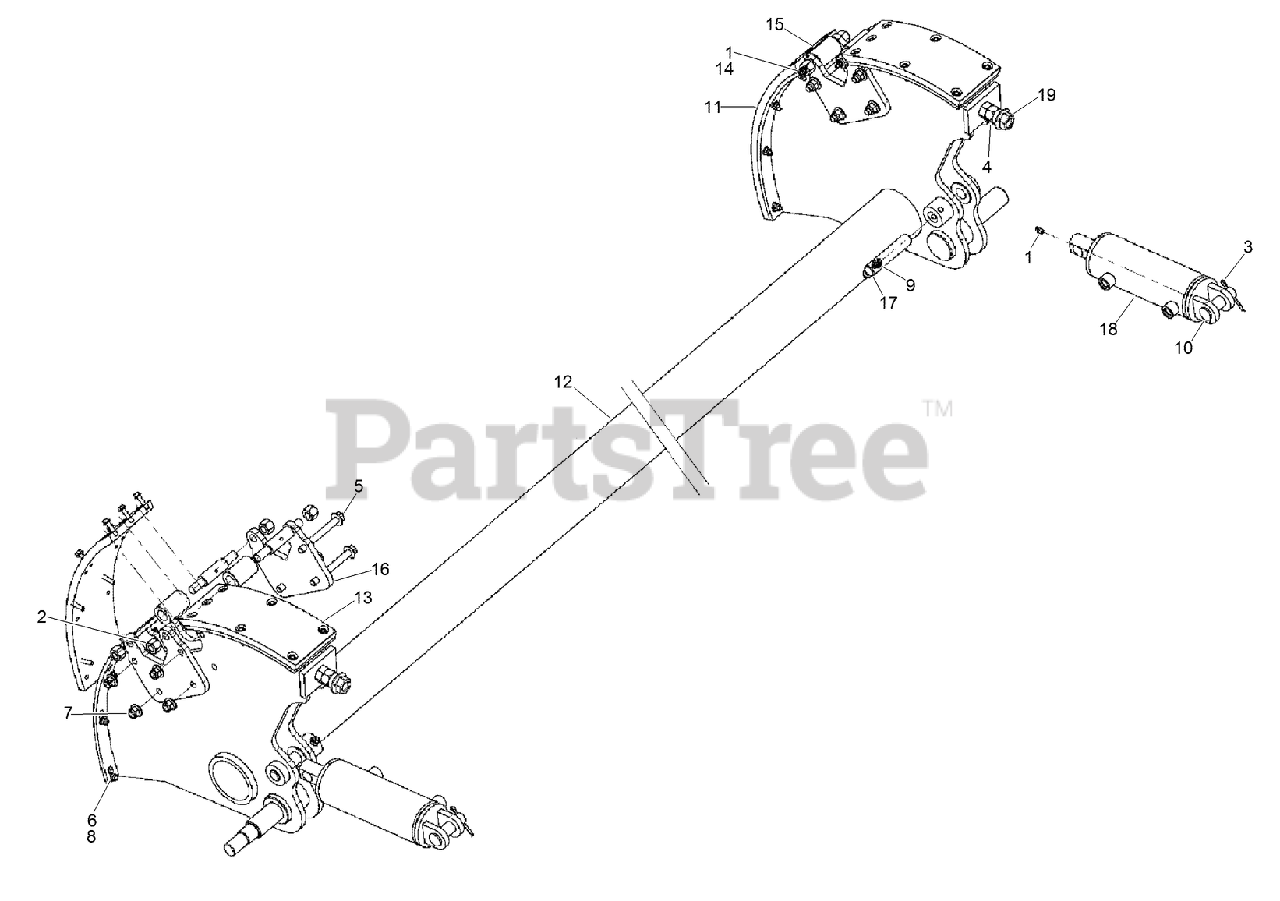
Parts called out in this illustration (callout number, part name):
1	FITTING-Lube 1/4-28 Tpr SAE-LT .54 Long
2	NUT - Prev Trq 1/2 GRA ZND NonDir
3	PIN-cotter, 5/32 x 1-3/4 inch
4	NUT - M16 Class 10 ZND
5	SCREW-FLANGE, METRIC
6	NUT, METRIC FLANGE PREVAILING - M6 Zinc
7	NUT-FLANGE, NYLOCK
8	SCREW, METRIC FLANGE w/BODY-M6 x 25
9	SCREW, METRIC FLANGE w/BODY - M6 x 50
10	PIN-CLEVIS
11	PAD-WEAR, ROD LOADER (LONG)
12	ASSEMBLY - Cam
13	PAD-WEAR, ROD LOADER (SHORT)
14	SHAFT-ROLLER, PIPE
15	TUBE-ROLLER
16	PLATE - Pipe Holder
17	PIN-STRAIGHT
18	SCREW-HH
19	HYD CYLINDER ASM
